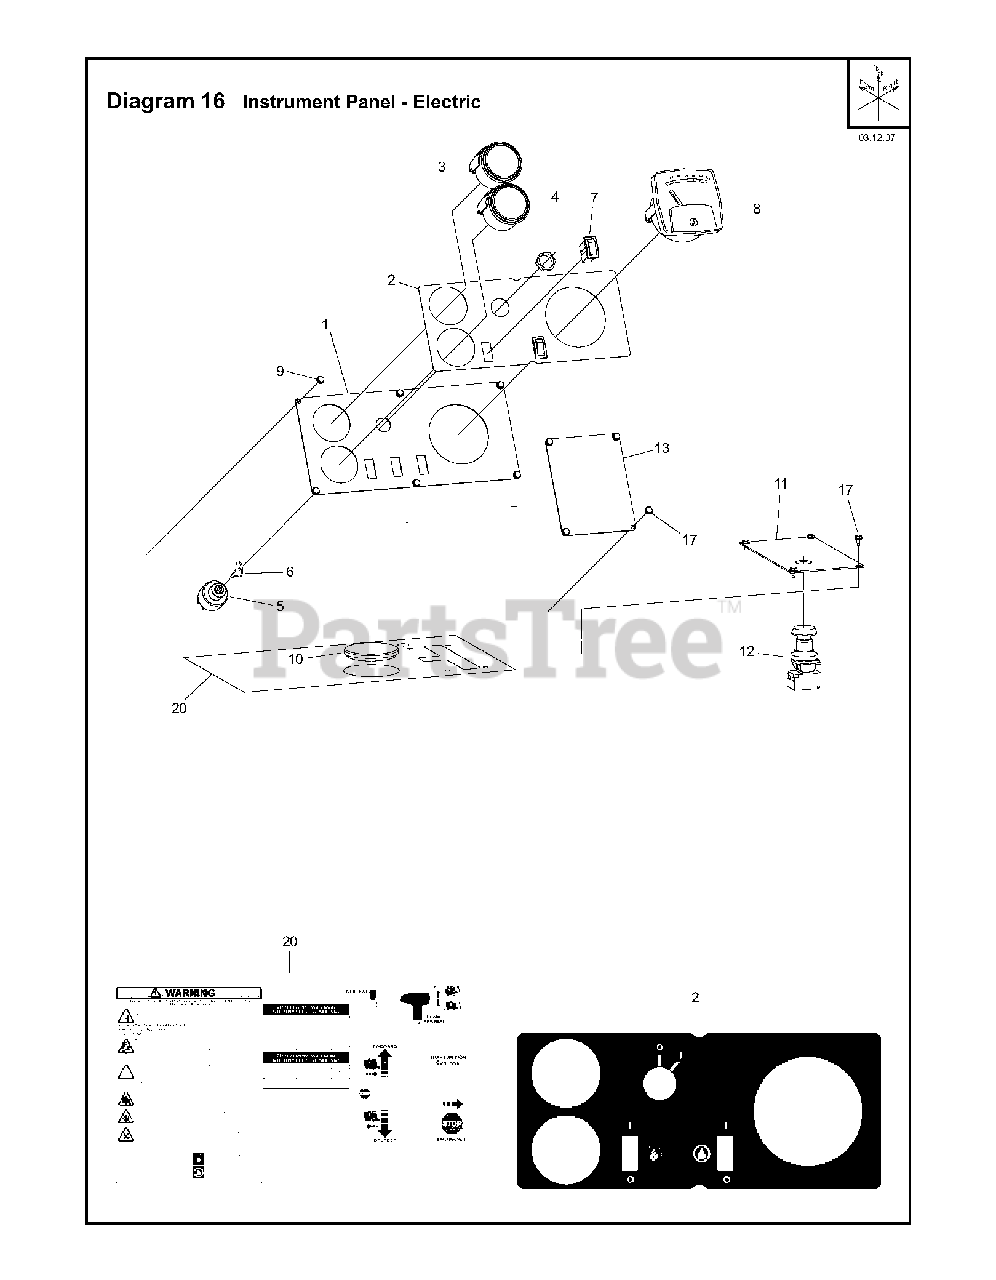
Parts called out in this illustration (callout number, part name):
4	GAUGE. HOUR METER
5	KEYSWITCH. IGNITION
7	SWITCH. ROCKER SPST
8	METER. MOTOR LOAD
9	HWHSTS. 10-24 x .375 TYPE F SL
12	SWITCH. MUSHROOM STOP
17	HWHSTS. 10-24 x .375 TYPE F SL
20	PULLEY.IMPELLER *SUBS/2*
